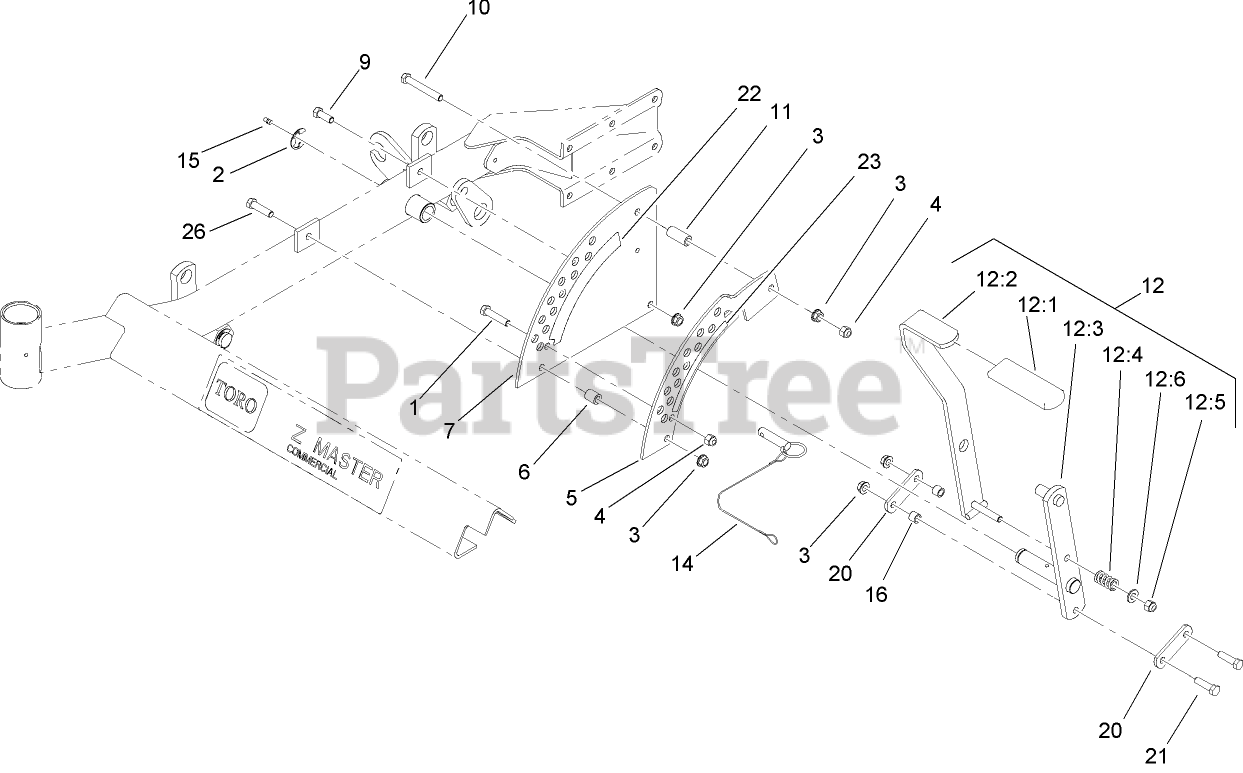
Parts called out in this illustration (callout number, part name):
1	SCREW-HH
2	RING-RETAINING, EXT
3	NUT-HHF, WHIZ
4	NUT-LOCK, NI
5	PLATE-LIFT, DECK
6	BUSHING-LEVER, LIFT
7	PLATE-LIFT, DECK
9	SCREW-HH
10	SCREW-HH
11	BUSHING-LEVER, LIFT
12	DECK LIFT HANDLE ASM
12:1	GRIP-LEVER, LIFT
12:2	HANDLE-LIFT
12:3	LIFT ARM ASM
12:4	SPRING-COMPRESSION
12:5	NUT-LOCK, NI
12:6	WASHER-FLAT
14	Hitch Pin ASM
15	FITTING-GREASE
16	Bushing
20	ARM-LIFT, DECK
21	SCREW-HH
22	DECAL-DECK HEIGHT, OUTER
23	DECAL-DECK HEIGHT, INNER
26	SCREW-HH
